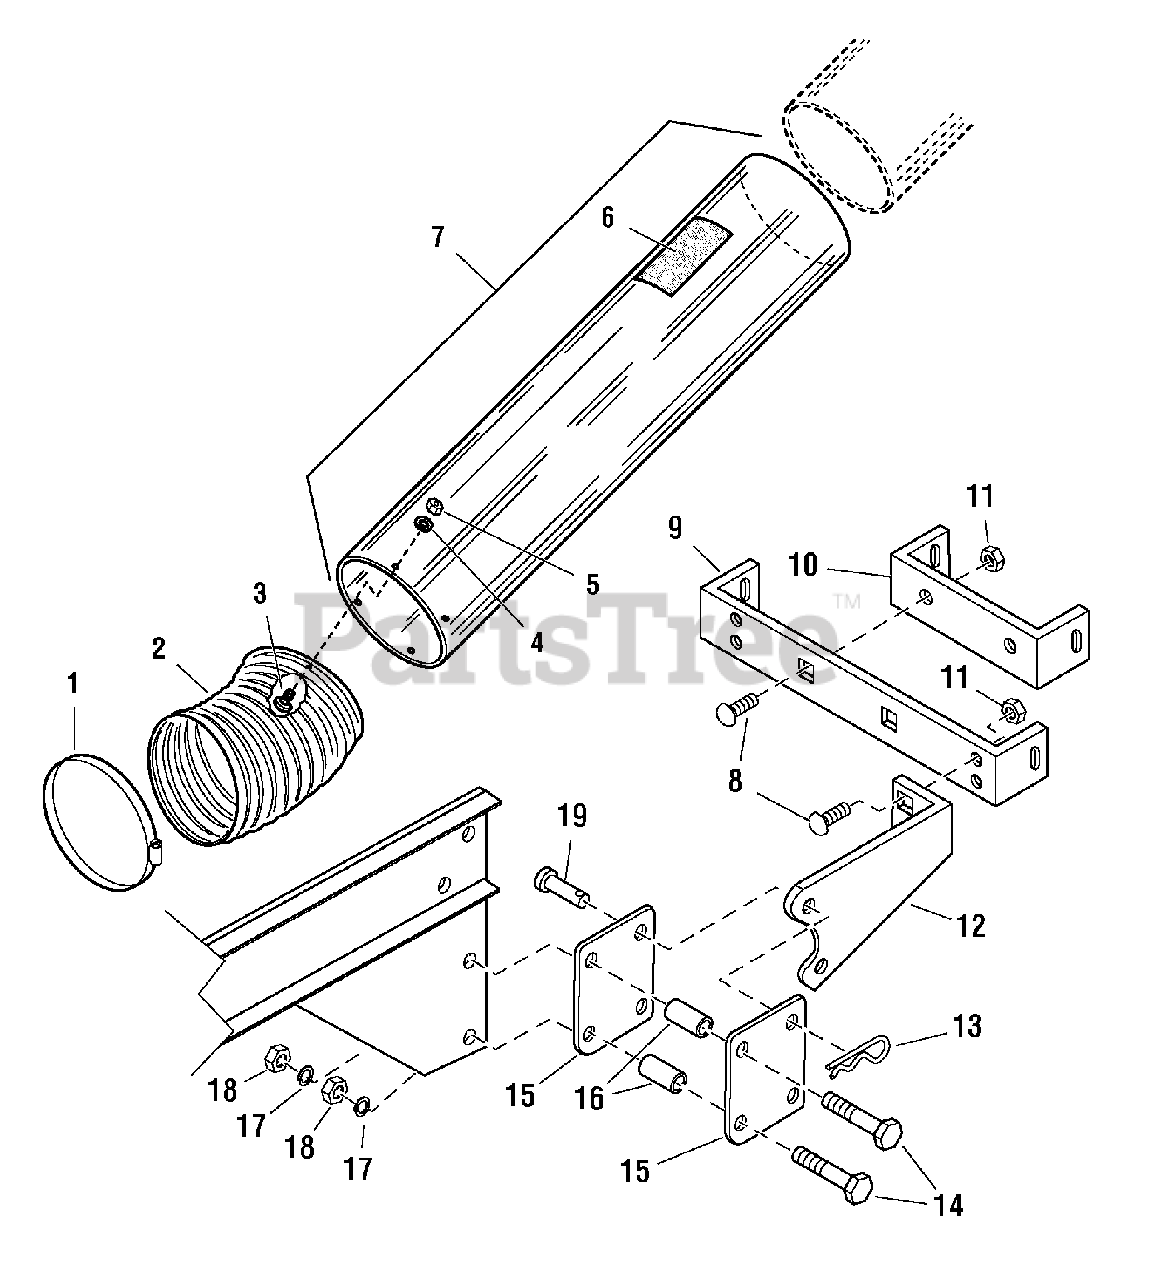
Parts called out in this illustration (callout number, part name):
1	CLAMP, Hose 6", Band Type
2	HOSE, Vac Col, 6 x 12
3	SCREW, Truss Head Phillips, #10-32 x 1/2
4	WASHER, #10-32
5	NUT, Hex Washer Assembly, #10-32
6	DECAL, Cleaning Instructions
7	TUBE & DECAL ASSEMBLY (Includes Ref. No. 6)
8	CARRIAGE BOLT, 3/8-16 x 1-1/4
9	HITCH, Cross Bar
10	HITCH, Inner
11	NUT, Hex, Nylock, 3/8-16
12	SIDE PLATE
14	CAPSCREW, Hex, 1/2-13 x 2-1/2
15	INNER SUPPORT
17	WASHER, Lock, 1/2
18	NUT, Hex, 1/2-13
19	PIN, Clevis
